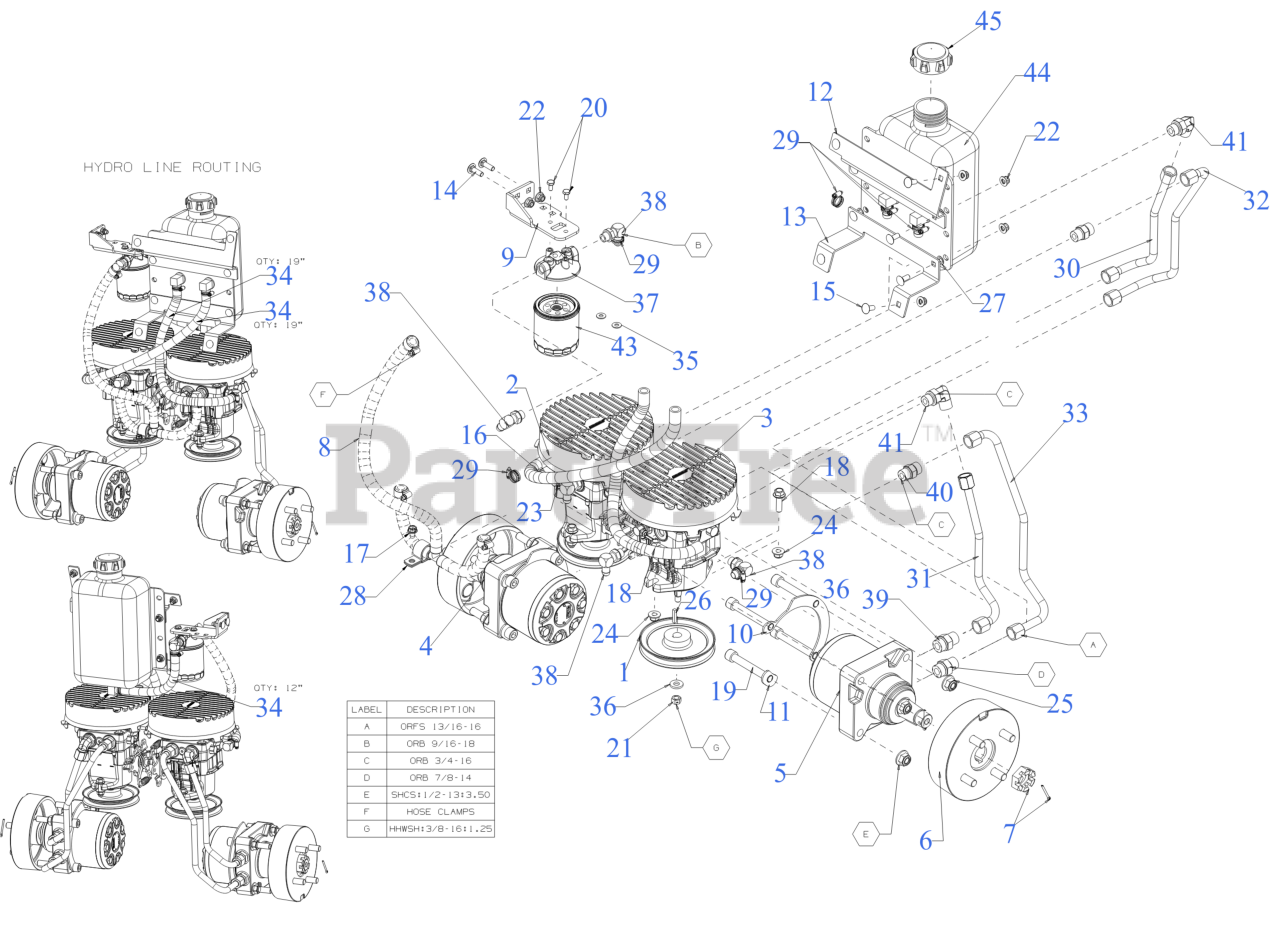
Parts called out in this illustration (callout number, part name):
1	PULLEY-HYDRO PUMP
2	HYDRO PUMP (RH)
3	HYDRO PUMP (LH)
4	HYDRO MOTOR W/O BRAKE (LH)
5	HYDRO MOTOR W/O BRAKE (RH)
7	HUB MOUNT HARDWARE
8	HYDRO DRAIN HOSE
8	HOSE CLAMP
9	FILTER MOUNT BRACKET
10	WHEEL MOTOR SHIM PLATE
11	WHEEL MOTOR LOWER SHIM PLATE
12	OIL RESERVOIR BRACKET
13	OIL RESERVOIR BRACKET (LOWER)
14	CARRIAGE BOLT 5/16-18 x 1.00
15	CARRIAGE BOLT 5/16-18 x .75
16	SCREW 1/4-20 x 2 GR5
17	SCREW 5/16-18 x .500
18	SCREW 3/8-16 x 1.25 GR5
19	HEX CAP SCREW 1/2"-13x3.5
20	SCREW 1/4-20X.5 GR5
22	FLANGE LOCK NUT 5/16-18
23	FLANGE LOCK NUT
26	SQUARE KEY 3/16 x 1.00
28	HOSE CLAMP 1.0"
29	HOSE CLAMP .75 ID
30	HYDRO TUBE (OUTSIDE) (LH)
31	HYDRO TUBE (OUTSIDE) (RH)
32	HYDRO TUBE (INSIDE) (LH)
33	HYDRO TUBE (INSIDE) (RH)
34	HYDRAULIC BULK HOSE 12"
34	HYDRAULIC BULK HOSE 19"
35	FLAT WASHER
36	FLAT WASHER
37	OIL FILTER ADAPTER
38	ELBOW FITTING
39	HYDRO FITTING 8 ORFS x 10 ORB
40	HYDRAULIC FITTING
41	HYDRAULIC ELBOW ADAPTOR
43	HYDRAULIC FILTER
44	HYDRO OIL TANK (1 GAL)
45	HYDRO TANK CAP
